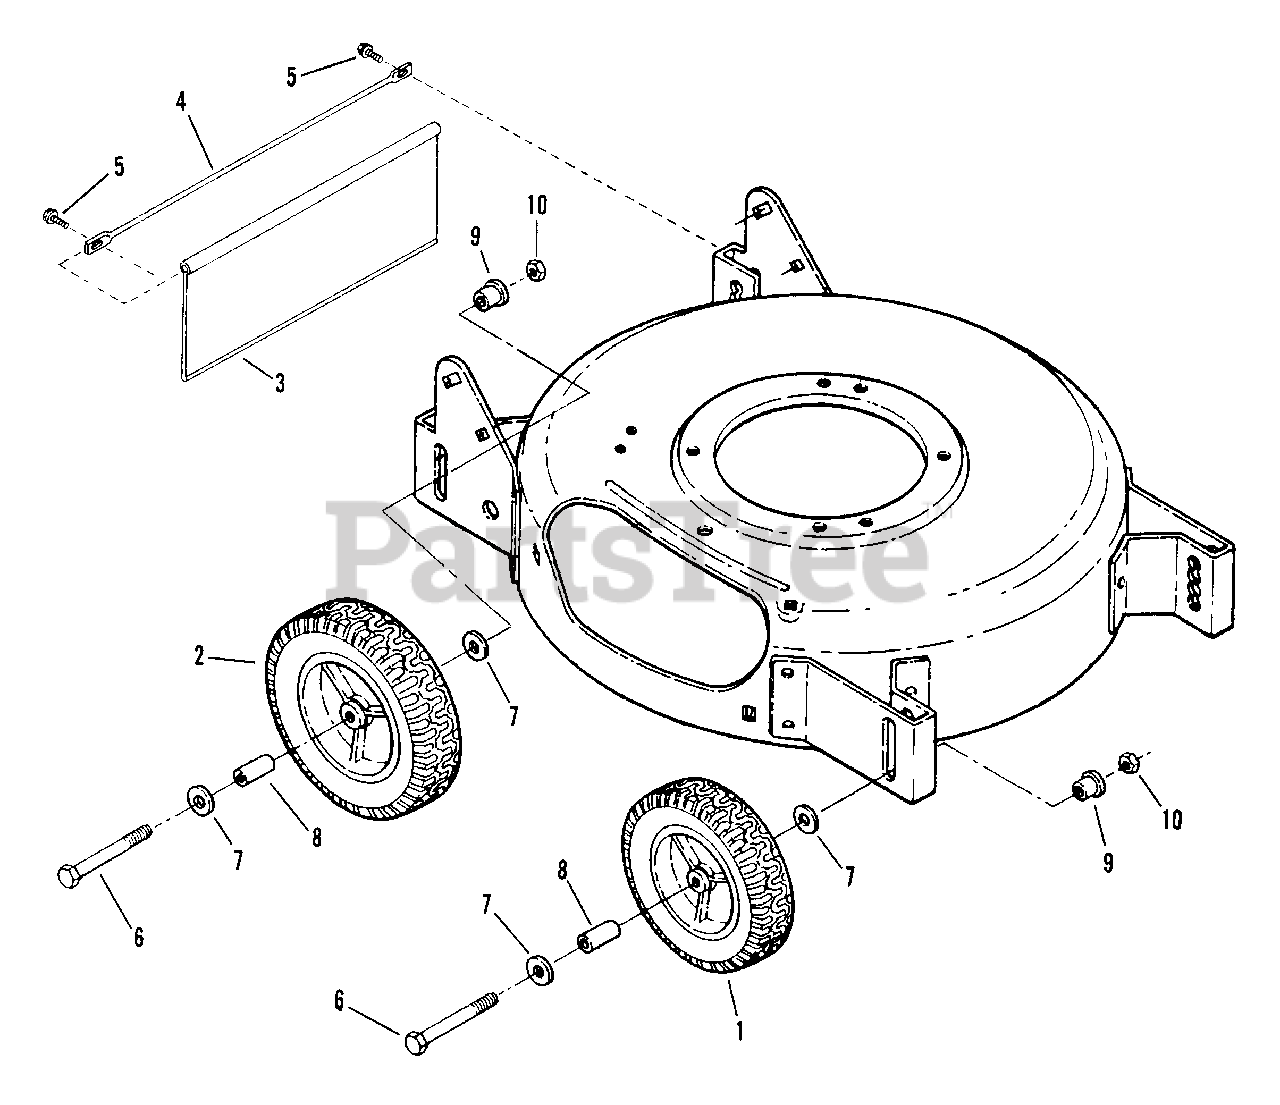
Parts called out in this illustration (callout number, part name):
1	WHEEL, Front 7 x 1.75
2	WHEEL, Rear 8 x 2.00
3	GUARD, Rear Foot
4	SUPPORT, Foot Guard
5	SCREW, #10-24 x 1/2" Hex Washer Self-Tap (Torx)
6	SCREW, 3/8-16 x 3-1/8" Hex Head Cap
7	WASHER, 3/8" Flat
8	BUSHING, Axle
9	BUSHING, Height Adjustment
10	NUT, 3/8-16 Hex Center Lock
